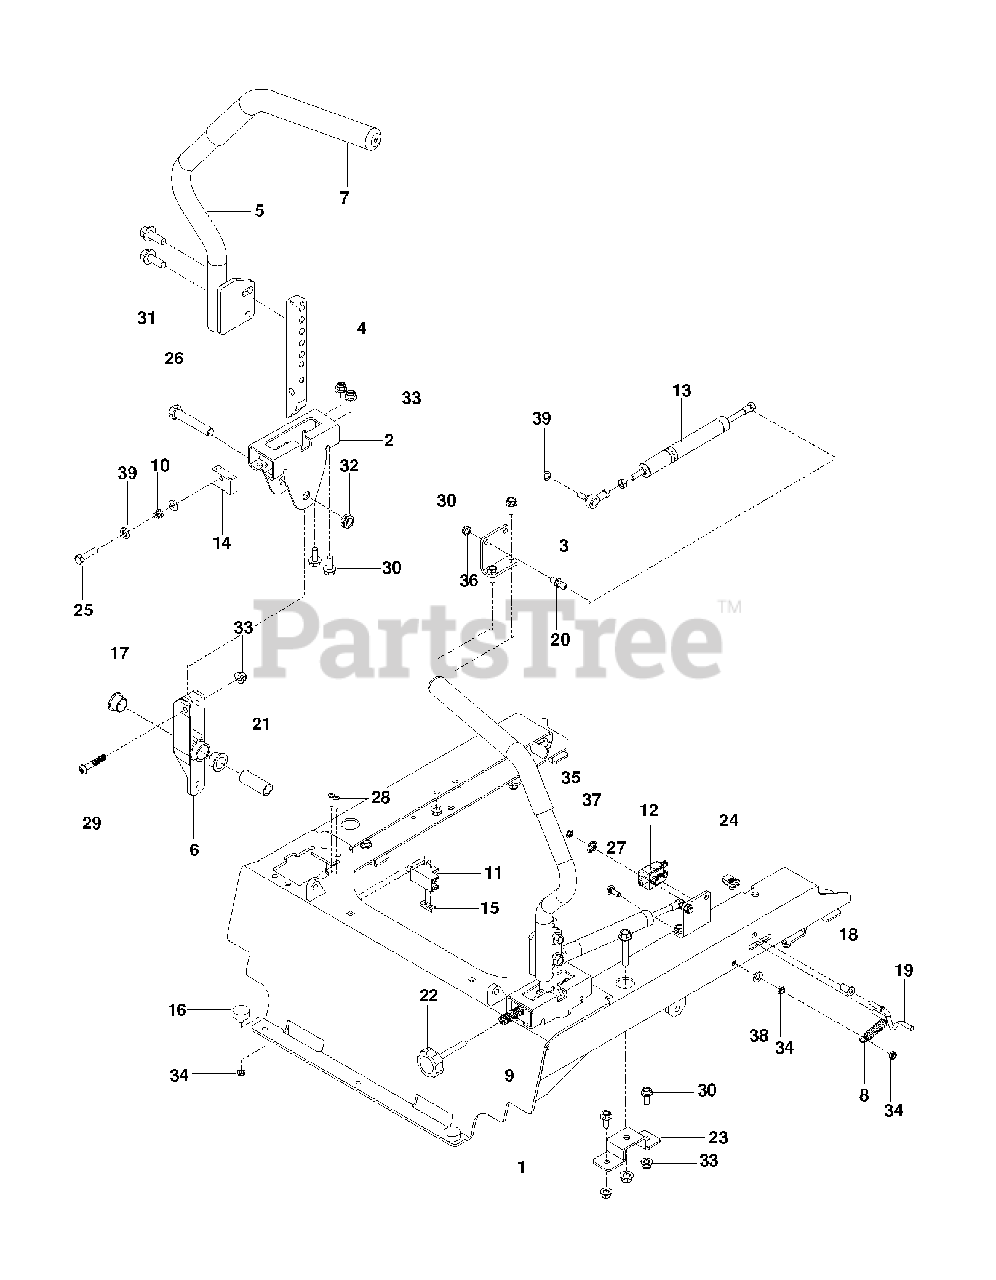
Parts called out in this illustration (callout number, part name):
1	FRAME SEAT MOUNT ORANGE
2	BRACKET, CONTROL
3	BRACKET.DAMPNER
4	LEVER, MOTION
5	LEVER.WITH GRIP.RT
6	LEVER.CONTROL.SHORT
7	GRIP - DRIVE LEVER 12"
8	SPRING, EXTENSION
9	SPRING COMPRESSION 2.0
11	SWITCH INTERLOCKT
12	SWITCH, BRAKE 3P
13	ASSEMBLY, DAMPENER
14	BLOCK.TRACKING
15	BLOCK, LOWER
16	BUMPER, 1/4-20 STUD, 1/4
17	BEARING, FLANGE
18	BUSHING, 1/4 FLANGE
19	LINK, SWITCH
20	STUD.BALL.10MM
21	SPACER, PIVOT CONTROL
23	MOUNT, MID-SECTION, BLK
24	U-CLIP 5/16-18 NUT RETAINER
25	BOLT, TAP 5/16-18
26	HCS 1/2C X 2 3/4
27	RHSNB 1/4C X 3/4
28	SCR #10-24 X .75 SKT HD BLK
29	SCREW 5/16-18 X 1 3/4 BTN-HD
30	HHFS 5/16-18 X 3/4
31	HHFS 3/8-16 X 1 GRD 5 ZD
32	NUT 1/2-13 HEX JM NYL
33	5/16-18 NYLOC FLANGE NUT
34	JAM NUT 1/4C (2 2 PW01)
36	NUT 5/16 NYLOC
37	NUT 3/8 PALNUT RTNG BLK PHOS
38	FLAT WASHER 5/16 SAE
39	WASHER 5/16 LOCK
